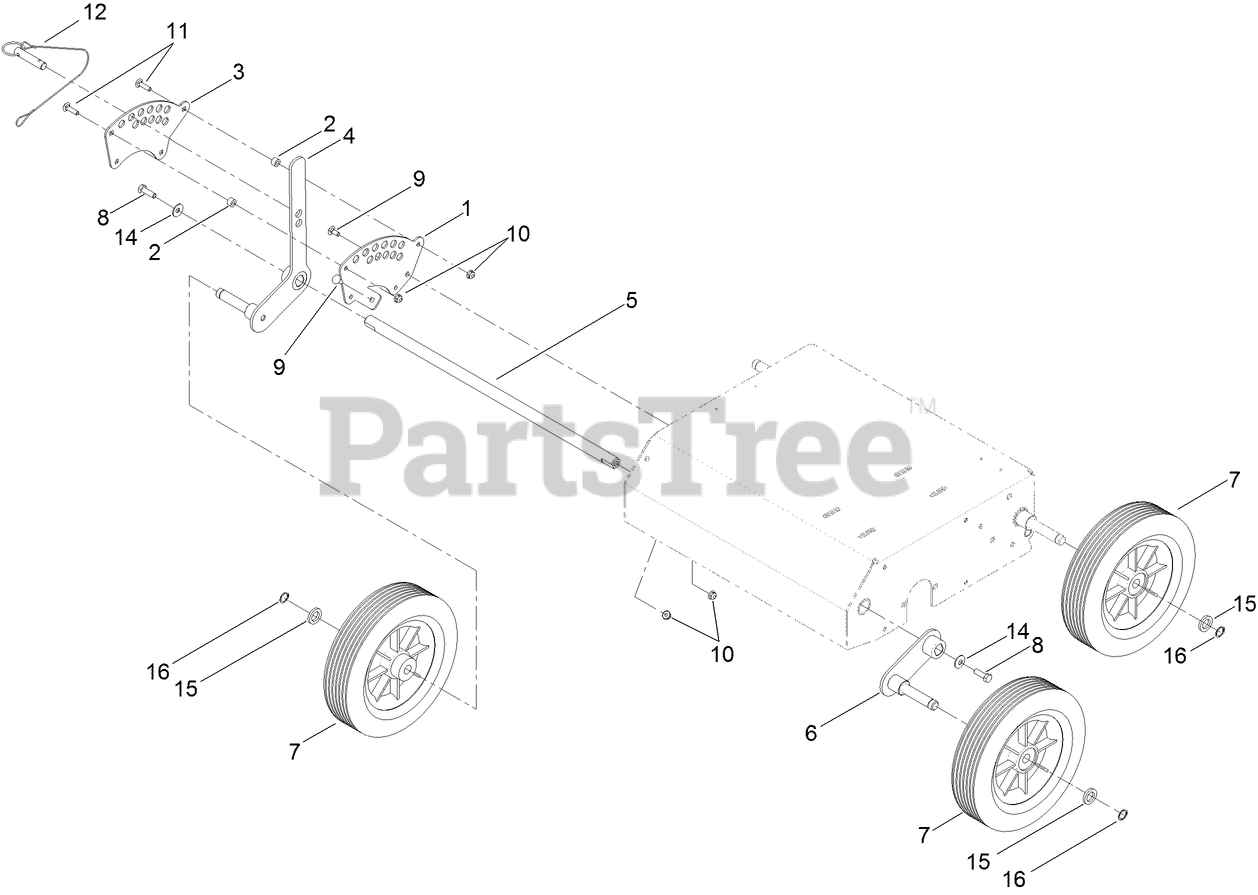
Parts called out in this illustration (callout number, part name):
1	BRACKET
2	SPACER
4	LEVER-HOC
5	SHAFT-PIVOT
7	WHEEL-TRANSPORT 10"
8	SCREW-HH
9	SCREW-CARR
10	NUT-HF
11	SCREW-CARR
12	PIN-HITCH
14	WASHER-BELLEVILLE
15	SPACER-BEARING
16	RING-SNAP, EXTERNAL
